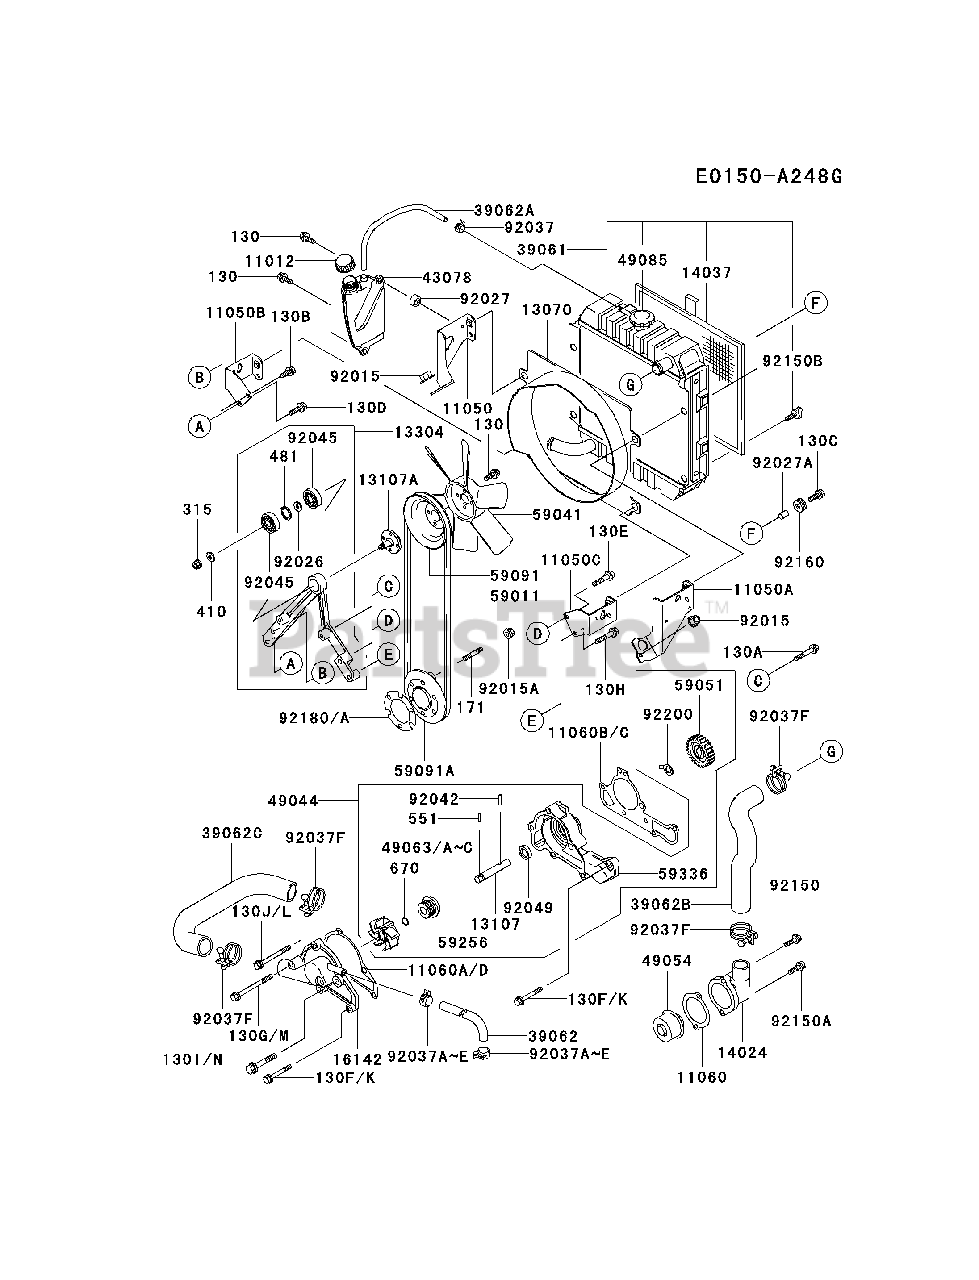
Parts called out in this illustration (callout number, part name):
130	BOLT-FLANGED
130A	BOLT-FLANGED
130B	BOLT-FLANGED
130C	BOLT-FLANGED
130D	BOLT-FLANGED
130E	BOLT-FLANGED
130H	BOLT-FLANGED
130K	BOLT-FLANGED
130L	BOLT-FLANGED
130M	BOLT-FLANGED
130N	BOLT-FLANGED
171	BOLT-STUD
315	NUT-HEX-FINE
410	W-PLAIN-S
481	CIRCLIP
551	PIN-DOWEL
670	O RING
92045	BEARING-BALL,6001DDUC3
92180	SHIM,T=0.6
92180A	SHIM,T=1.2
